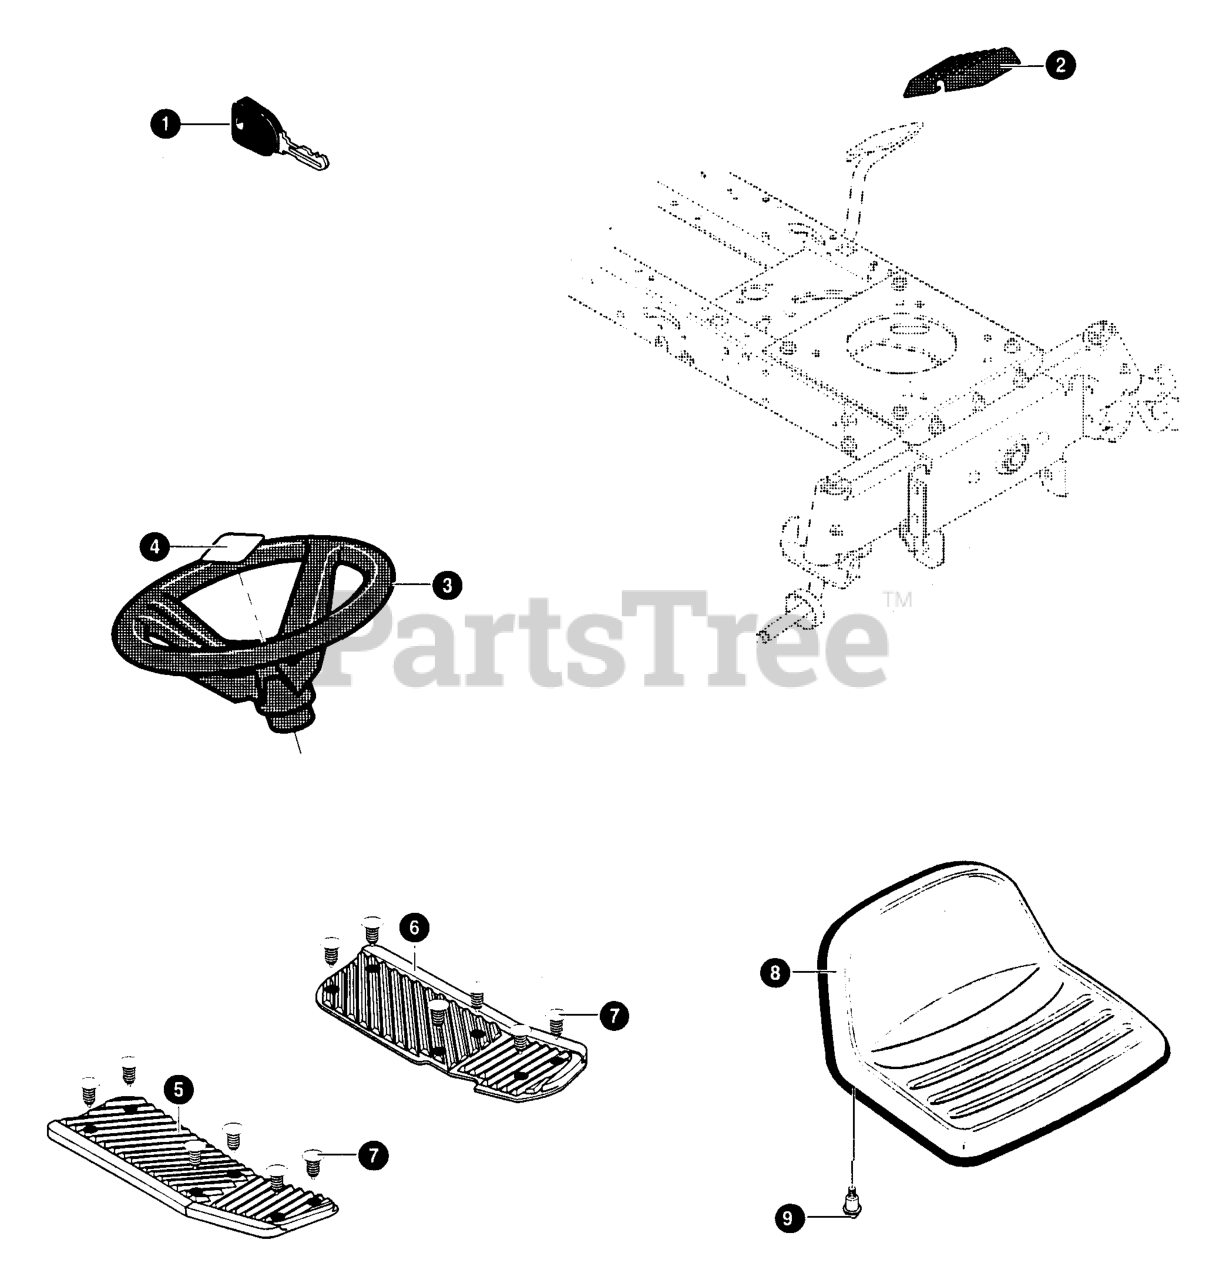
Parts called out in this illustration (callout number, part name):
1	IGNITION KEY
2	PAD, CLUTCH/BRAKE
3	STEERING WHEEL
4	INSERT, 4-SPOKE
5	FOOTREST PAD RH
6	FOOTREST PAD LH
7	RATCHET FASTENER
9	BOLT, .375X.255 HHSH 5/16-18
